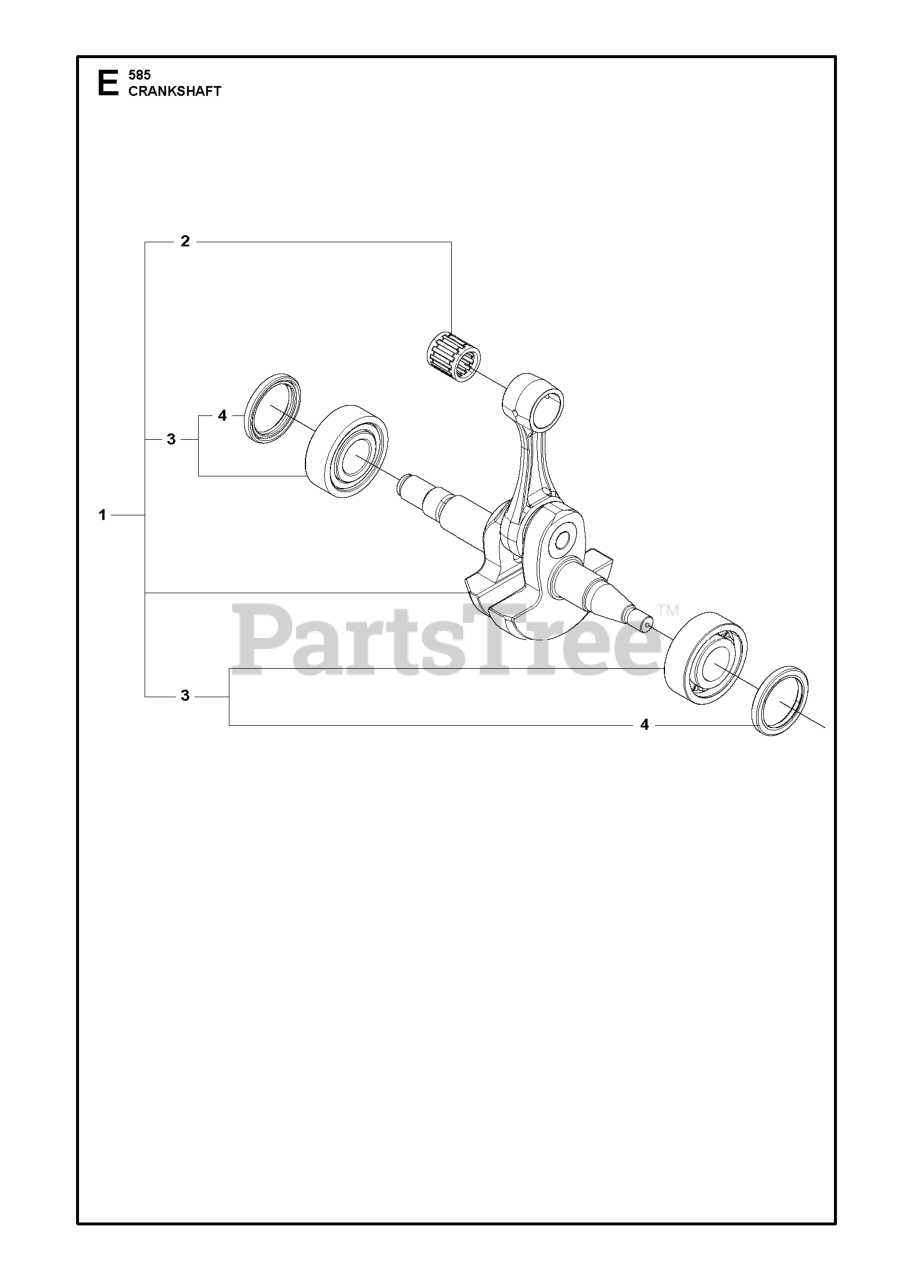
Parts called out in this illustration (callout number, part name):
1	CRANKSHAFT KIT 90 CC SPARE PAR
2	NEEDLE BEARING 13X17X17
3	BALL BEARING
4	SEALING RING
